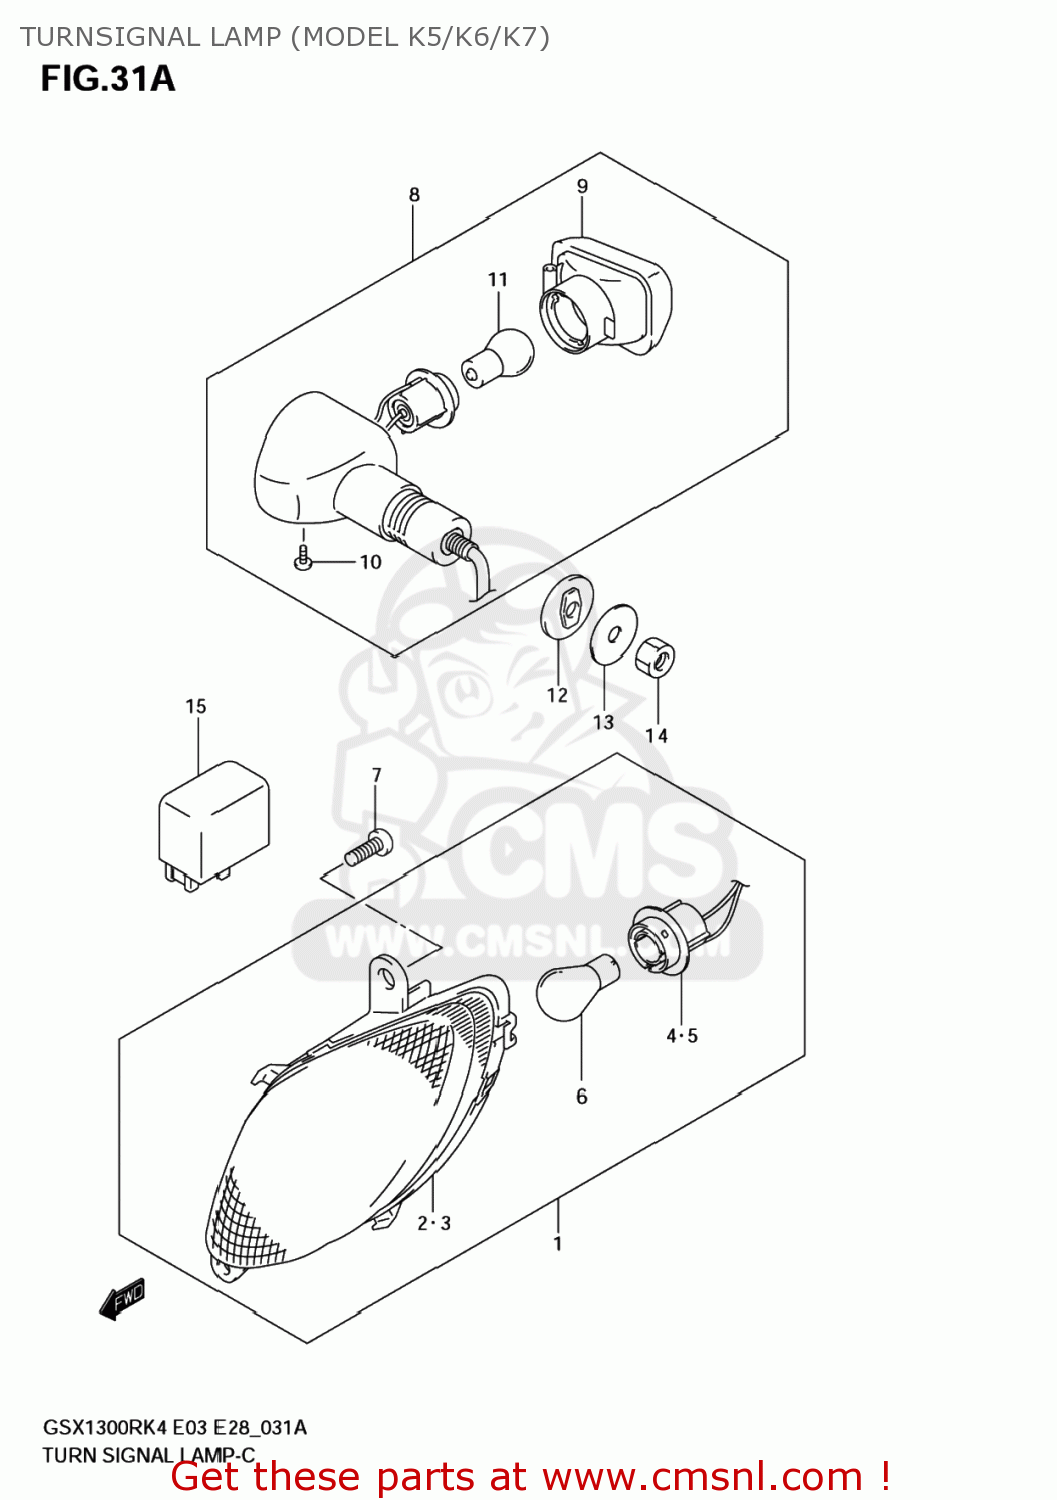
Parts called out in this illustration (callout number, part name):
1	LAMP ASSY,FR TURN SIGNAL,R
2	LAMP UNIT,R
3	LAMP UNIT,L
4	SOCKET & CORD,R
5	SOCKET & CORD,L
6	BULB(12V21W,AMBER)
7	SCREW
8	LAMP ASSY,RR TURNSIGNAL,R
9	LAMP UNIT
10	SCREW
11	BULB(12V21W,AMBER)
12	SPACER,RR TURNSIGNAL
13	WASHER(10.5X30X2.3)
14	NUT
15	RELAY ASSY,TURNSIGNAL LAMP
